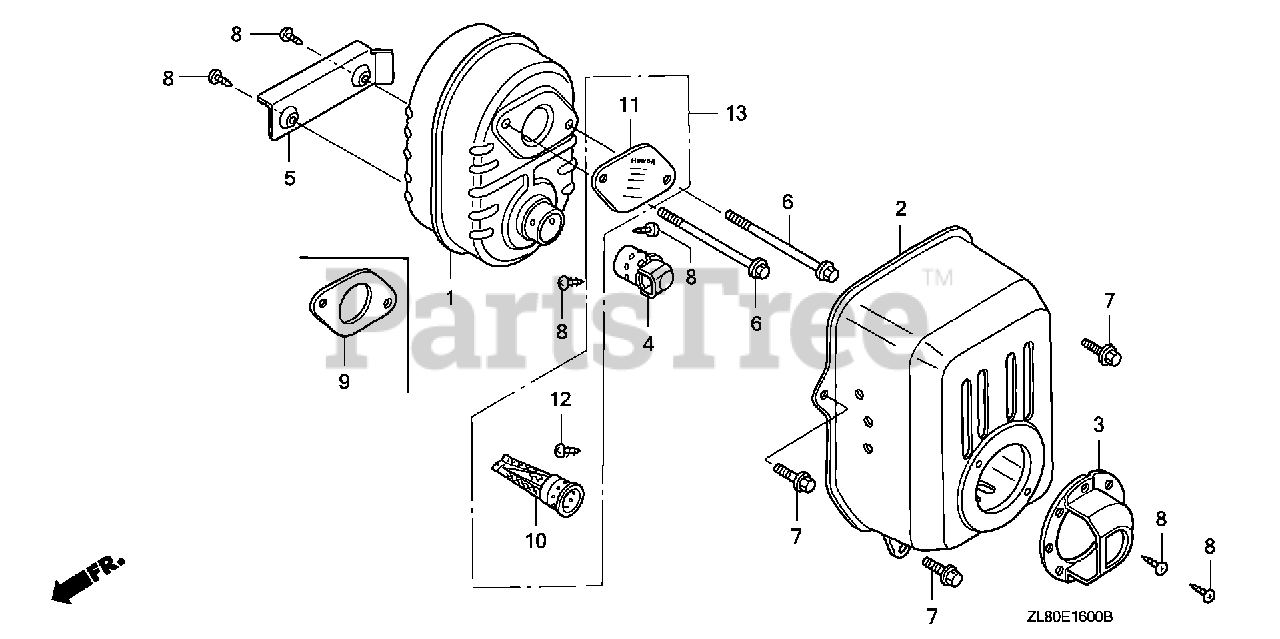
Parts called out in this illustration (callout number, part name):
2	PROTECTOR, MUFFLER
5	SHROUD, MUFFLER
6	BOLT, FLANGE (6X79) (CT200)
7	BOLT, FLANGE (6X12) (CT200)
8	SCREW, TAPPING (4X6)
9	GASKET, MUFFLER
10	ARRESTER, SPARK
11	PLATE, ARRESTER NUMBER
12	SCREW, TAPPING (4X6)
